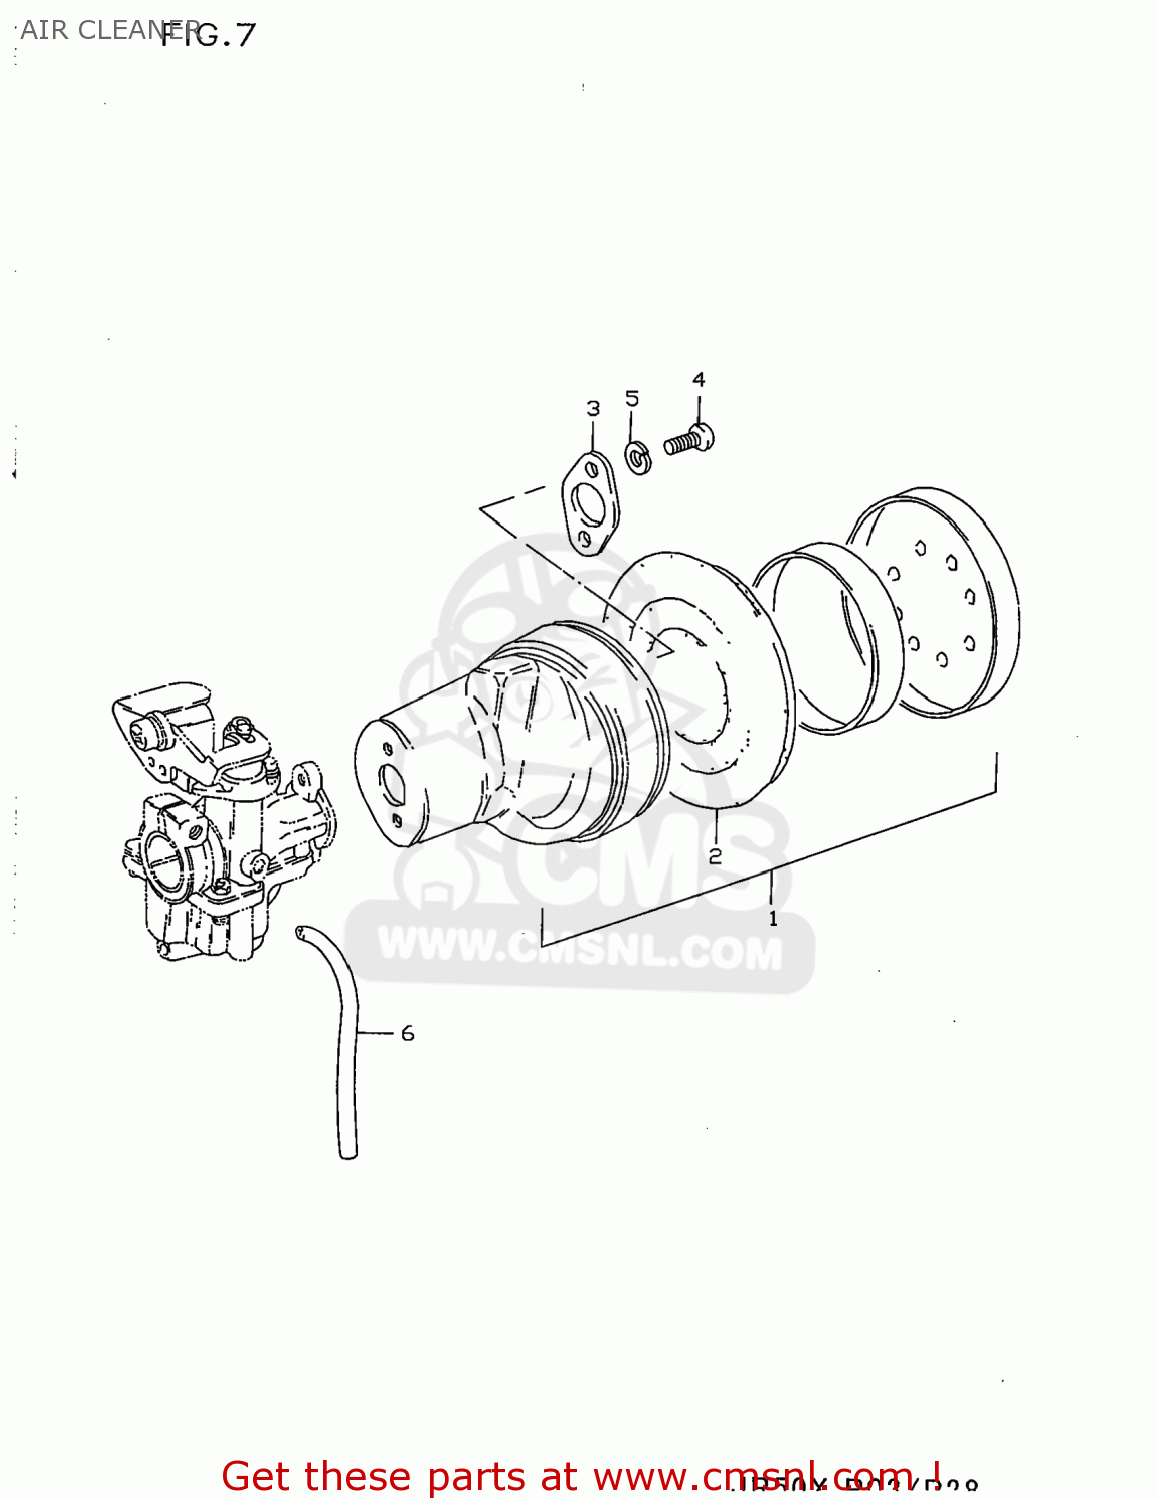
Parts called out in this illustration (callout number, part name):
1	CLEANER ASSY,AIR
2	FILTER,AIR CLEANER
3	PLATE,AIR CLEANER
4	SCREW
5	LOCK,WASHER
6	HOSE(3X5X600)
